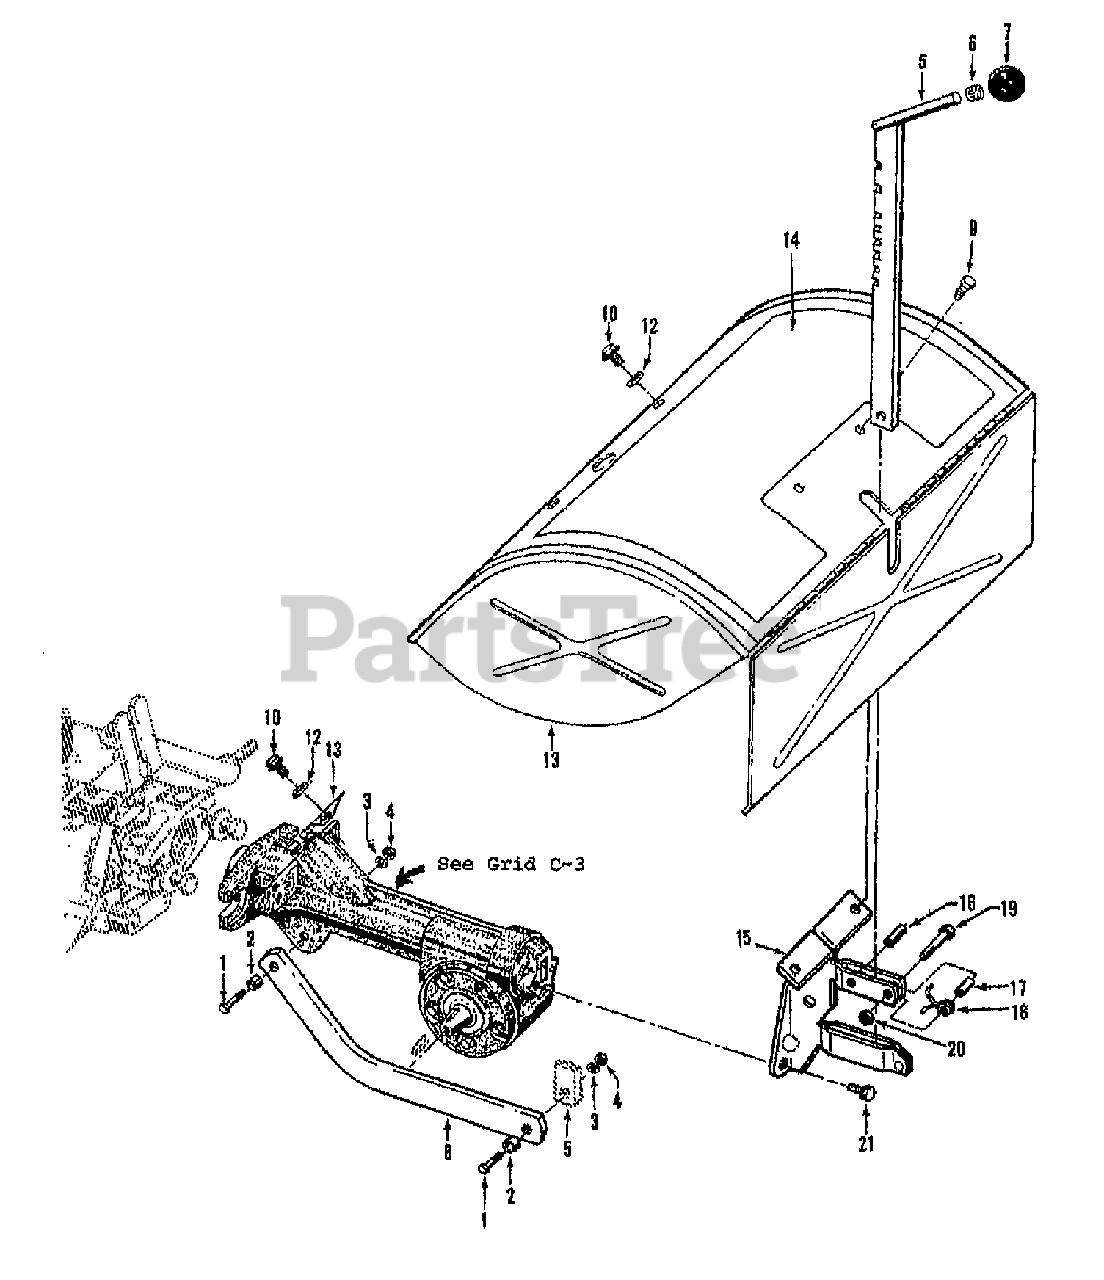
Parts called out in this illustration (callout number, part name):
1	SCR-HH 3/8-16X1.25
2	BUSHING-.5X.375X.3
3	WASHER-LK .375 @ DEPL
4	NUT-HEX 3/8-16 ZP
5	DEPTH REGULATOR W/KNOB
6	RING-TOLERANCE .5325 ID
7	KNOB-CONTROL
8	BAR-DRAG RED
9	SCR-HWH 1/4-20 X .5 STH
10	SCR-HFLK 5/16-18X.75 ZP
11	THIS REF. NO. NOT USED
12	WASHER-#1.125X.344 ZP
13	HOOD W/DECALS OPC SERVICE
14	DECAL-HOOD INST
15	BRKT W/ROLL PIN (9308)
16	PIN-ROLL .25 X 1
17	SPACER-.250X.343X.375
18	SPRING-TORSION
19	SCR-HH 1/4-20X1.0
20	NUT-LK 1/4-20
21	SCR-HFLK 5/16-18X.62 G5ZP
